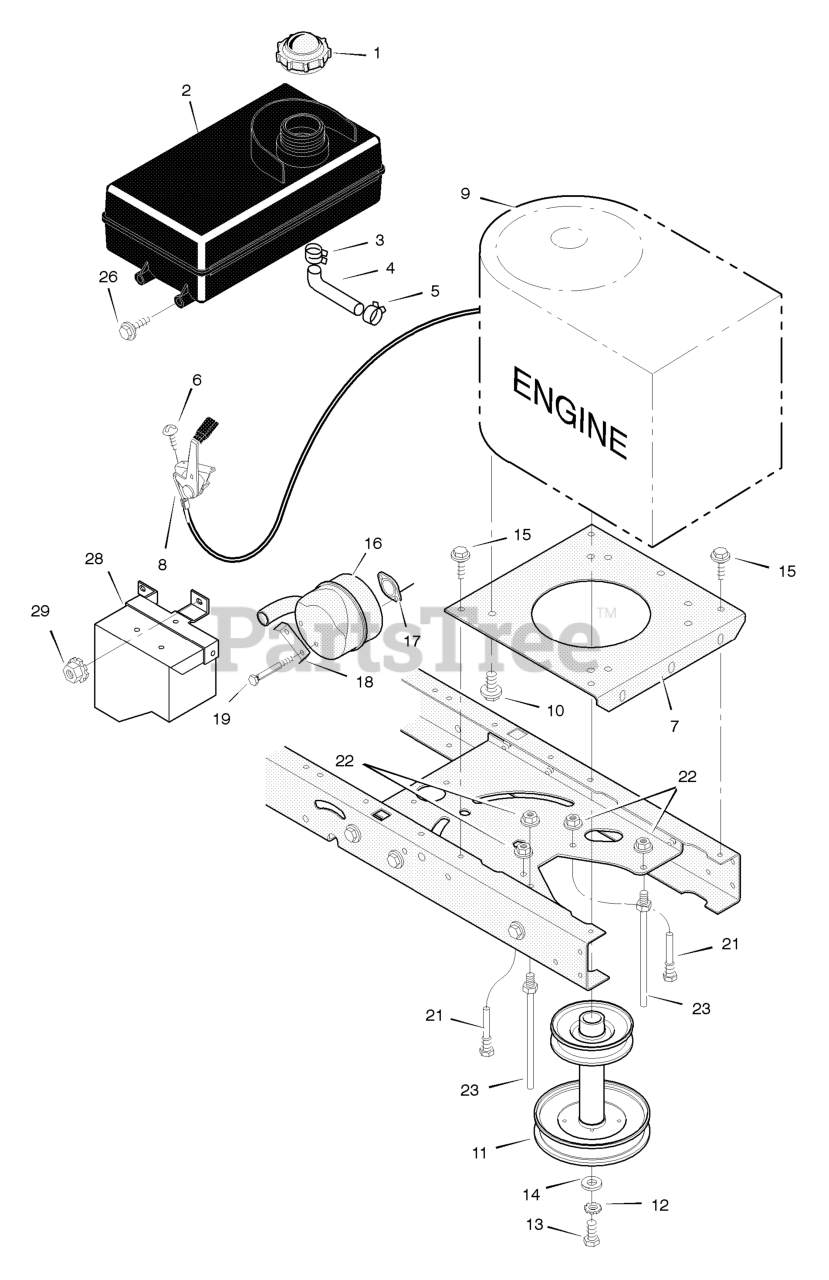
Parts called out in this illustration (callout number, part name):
1	Fuel Cap
2	Fuel Tank
3	Hose Clamp
4	Fuel Line (must cut to length)
5	Hose Clamp
7	Plate, Engine
8	Throttle Control
9	Engine, Tecumseh *
10	Bolt, Engine Mount
11	STACK PULLEY ASSEMBLY
12	Lockwasher
13	Bolt, Hex
16	Muffler
17	GASKET, Exhaust
18	Lock, Screw
21	Guide, Belt
22	Nut, Flange
23	Guide, Belt
28	Heat Shield Assembly - Muffler
